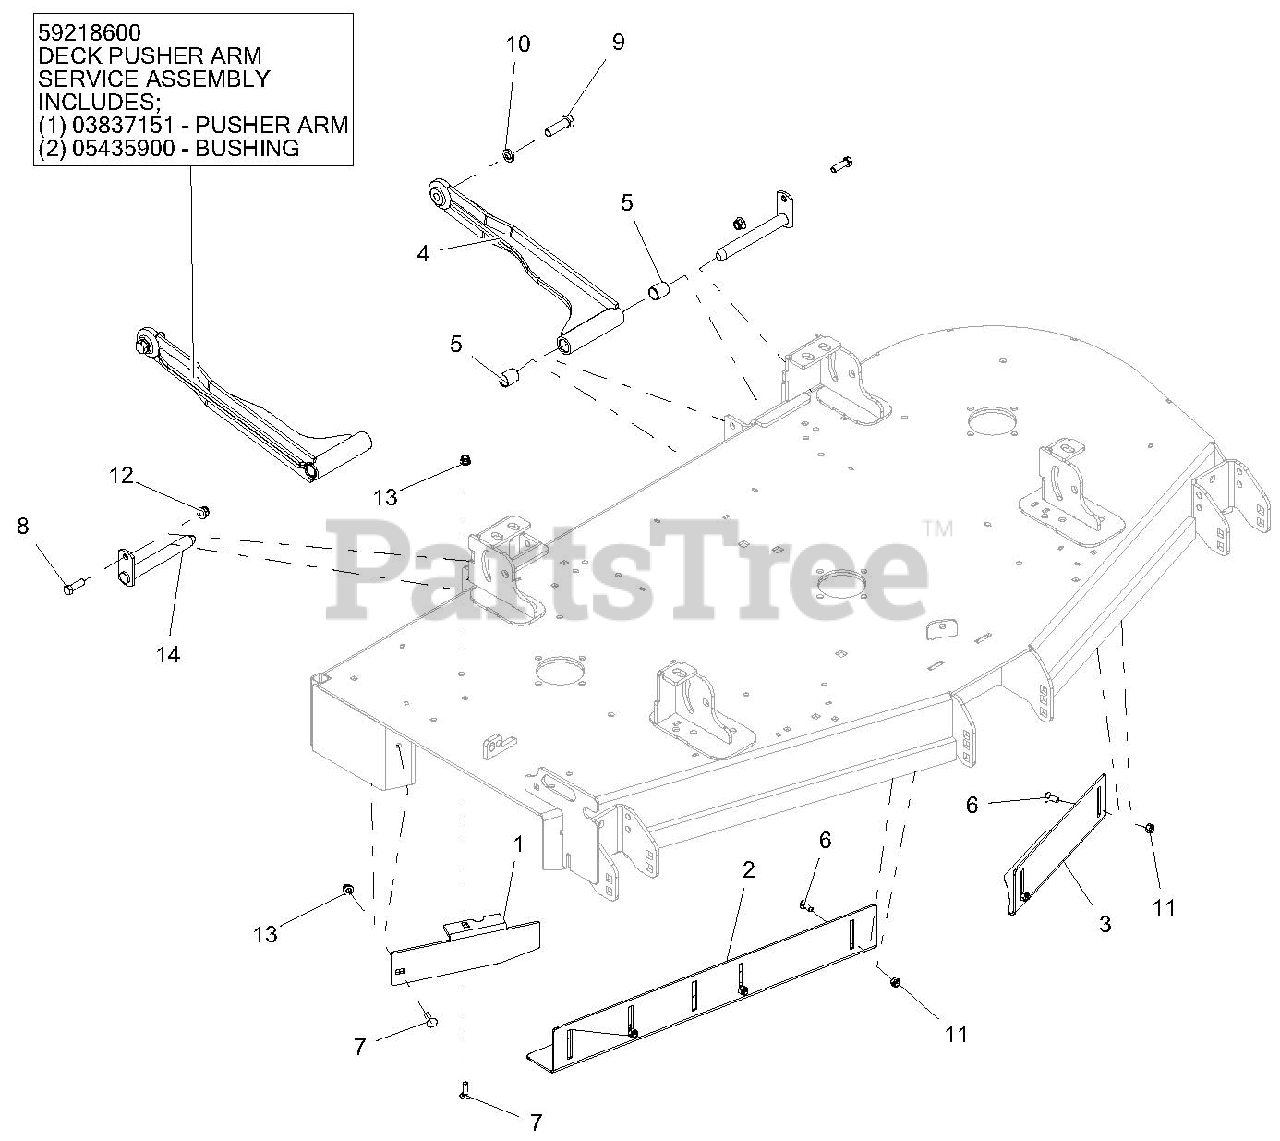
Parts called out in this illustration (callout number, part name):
1	BAFFLE, 60" DISCHARGE
2	BAFFLE, 60" RH VACUUM
3	BAFFLE, 60" LH VACUUM
4	WMT, DECK STABILIZER ARM-BLACK
4	DECK PUSHER ARM SERVICE ASSEMBLY
4	PUSHER ARM
4	BUSHING
5	BRG, .750 X .875 X 1.000
6	BLT-RDHDSQNK .31-18X.75 G5 YWZC
7	BLT-RDHDSQSHNK .31-18X1.00 G5 Y
8	BLT-HEX .38-16X1.25 GR5 YWZC
9	BLT-HEX .50-13X1.75 GR5 YWZC EP80
10	WSHR-LK .50X.125 REG YWZC
11	NUT-LK-NYL .312-18 YWZC
12	NUT-LK-NYL-FLG .38-16 YWZC
13	NUT-LK-NYL-FLG .31-18 YWZC
14	WLDMT, MOWER MTG. PIN
